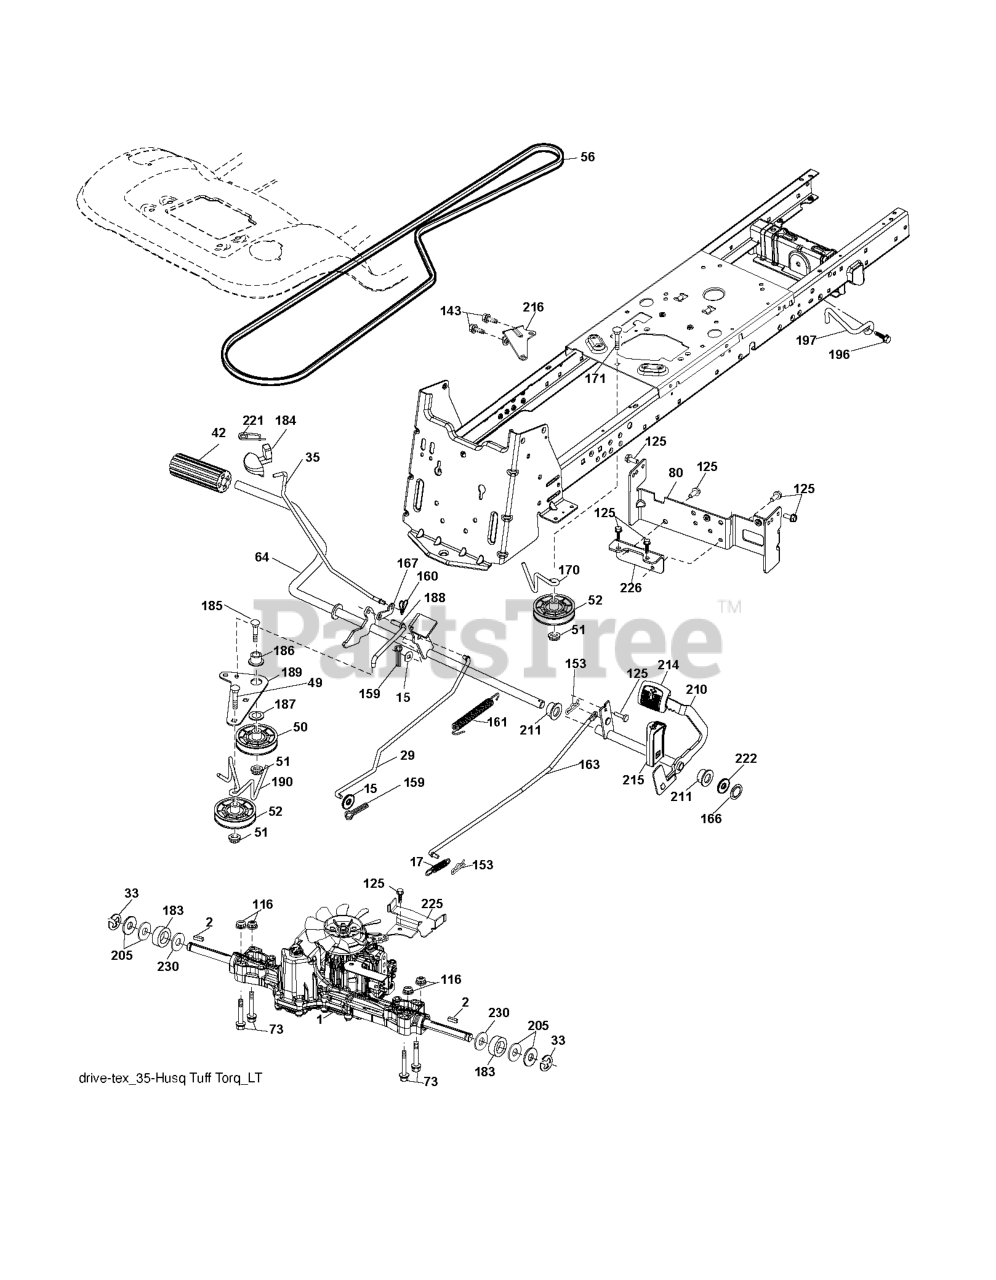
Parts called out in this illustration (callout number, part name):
2	SQUARE KEY
15	WASHER
17	SPRING.BRAKE.K46.GREEN
29	ROD.BRAKE.K46
35	ROD.CNTRL.PARK.PREDATOR.LT.TEX
42	PEDAL COVER T
50	IDLER.FLAT.910.OFFSET
51	NUT LOCK FLG 3/8-16 UNC
52	IDLER.V-GROOVE.910.OFFSET
56	V-BELT.MOWER.92.40.42/K46
64	SHAFT.ASM.PEDAL.BRK.CNTR
73	BOLT HEX 5/16-18 GR 5
80	STRAP.TORQUE.HG3000/K46
116	NUT LOCK HEX FLANGE 5/16-18
125	SCREW
143	Screw 5/16-18 x 1/2 Hex, Self Tapping 5/16-18 x 1/2
153	RETAINER M
159	COTTER PIN
160	RETAINER CLIP
161	SPRING.RETURN.CLUTCH.2006
163	ROD.CONTROL.PEDAL.K46
166	NUT.PUSH.625.2006
167	LATCH.BRAKE.SPRING
170	KEEPER.V-IDLER.CENTER.
183	SPACER AXLE
184	HANDLE PARKING BRAKE
186	SPACER.RETAINER
187	WASHER 12/32X2X10GA
188	RP.LINK.CLUTCH.GROUND.DRIVE
189	BELLCRANK.GROUND.DRIVE.TEX.
190	KEEPER.BELLCRANK.DRIVE
196	SCREW 3/8-16X1
197	LINK.CLUTCH.ANIT-ROTAT
210	ROCKER.ASM.PEDAL.CONTR
211	BEARING.NYLON
213	KNOB.CONTROL.CRUSIE.HU
214	PEDAL.FORWARD.TEX.GT.4
215	PEDAL.REVERSE.TEX.GT.4
216	BRACKET.PULLEY.IDLER.W/TEX
221	RETAINER.SPRING.CLIP.H
222	WASHER 21/32 X 1-1/4 X 10 GA.
225	KEEPER.BELT.TRANSAXLE.K46
226	BRACKET.MOUNT.TORQUE.K46.TLT
230	WASHER.HARDENED
